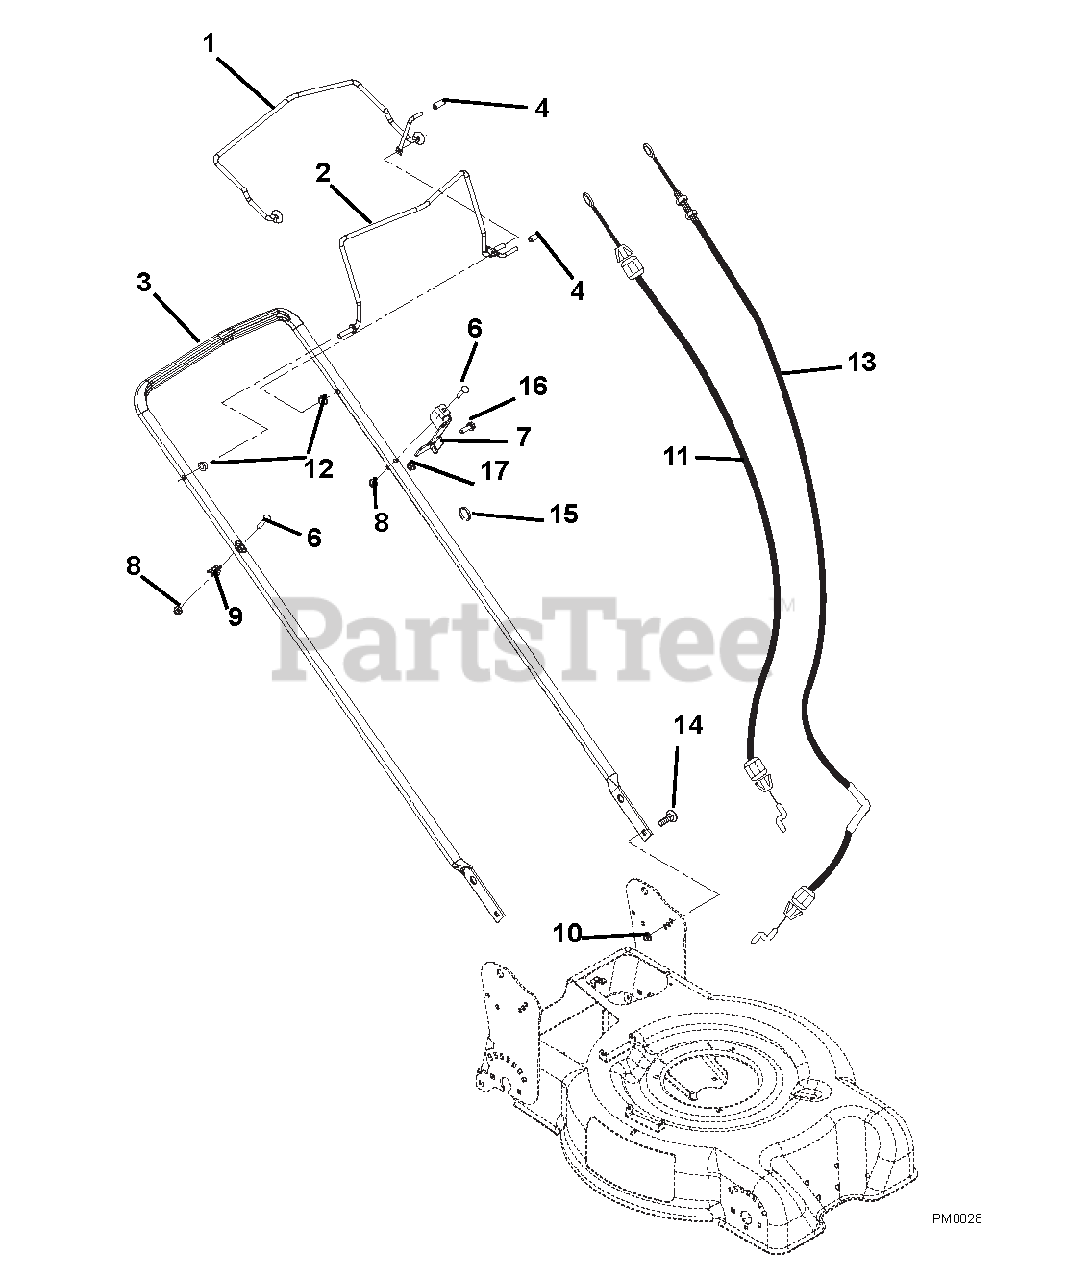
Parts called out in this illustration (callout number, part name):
1	BAIL, CLUTCH
2	BAIL, OPERATOR PRESENCE
3	HANDLEBAR, WBLM
4	CAP, VINYL, .25 ID
5	CAP, VINYL, .25 ID
6	BLT-RDHDXLSQNK.25-20X1.25 G5ZC
7	ANCHOR, CABLE - THUMB ADJUST
8	@NUT-LK-TOP-FLG .25-20 YWZC
9	GUIDE - PULLCORD
10	@NUT-SPNLK-FLG .312-18 YWZC
11	CABLE, OPERATOR PRESENCE
12	BSHG-FLG .325X.444X.440X.560
13	CABLE, TRACTION - THUMB ADJUST
14	@BLT-RHDSSQNK .31-18X.75 G5YZ
15	CONDUIT CLIP
16	@BLT-HEX .25-20X1.25 GR5 YWZC
17	@NUT-LK-TOP-FLG .25-20 YWZC
